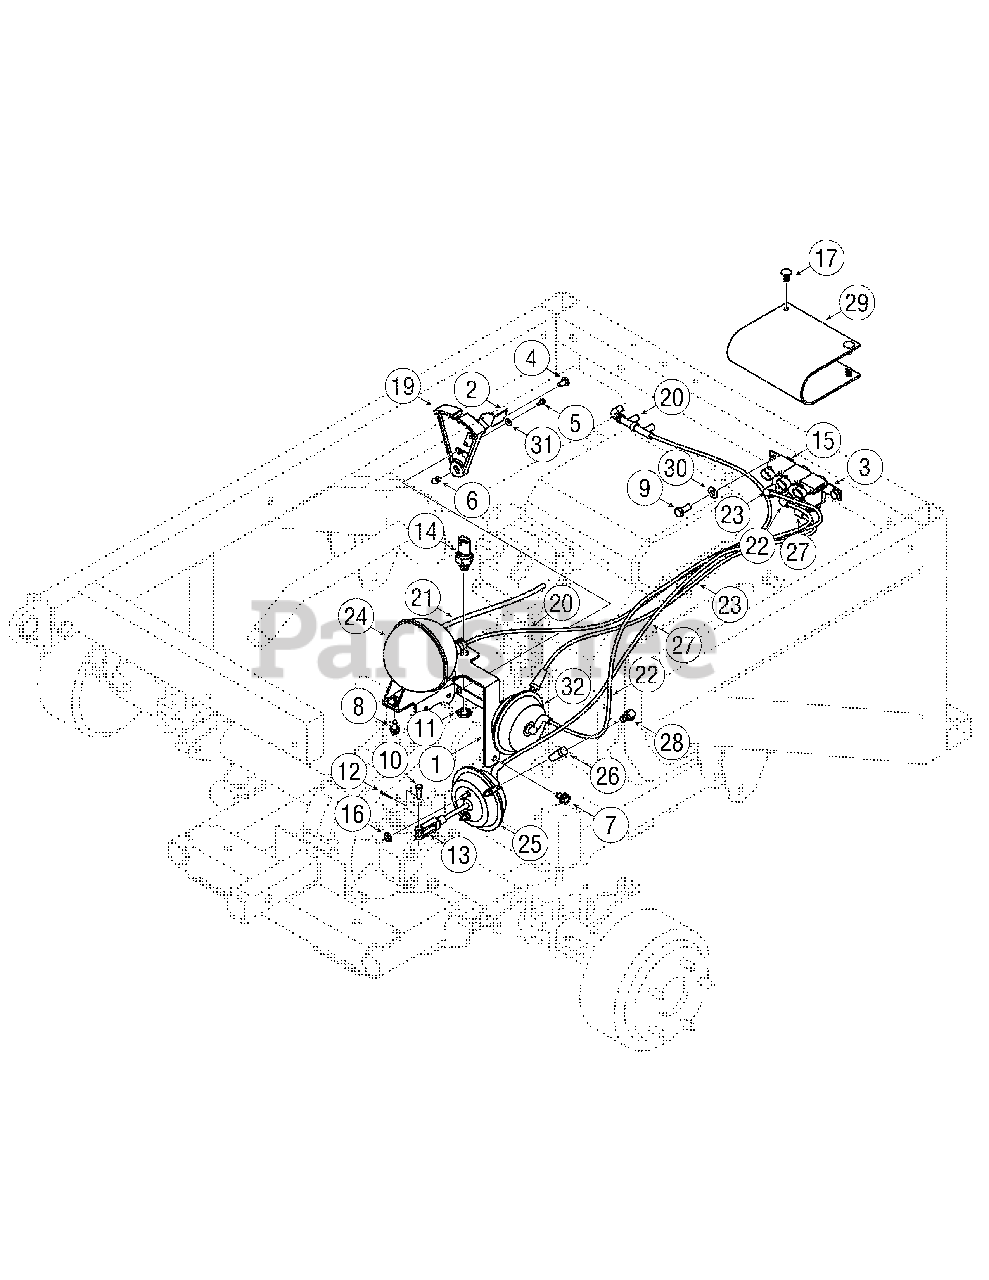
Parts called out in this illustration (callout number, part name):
1	Mounting Brkt., Vacuum Actuator
2	Bracket, Shift
3	Bracket, Vac Relay
4	Screw, 1/4-20 x.5
5	Screw, Hex. #8 - 18 .375
6	Screw, Set, 5/16-24 x .50 LG
7	Screw, 5/16-18
8	Screw, 1/4-14
9	Screw, 5/16-18 x .75 Hex
10	Pin, Yoke 1/4
11	Nut, Hex 9/16-18
12	Pin, Cotter 1/16x.750
13	Yoke, 1/4-28
14	Switch, Neutral
15	Solenoid, Kit Vacuum Actuator
16	Self Threading Nut
17	Clip, Panel Retainer
18	Cable Tie
19	Arm, Shift
20	Hose, Res
21	Hose, Manifold Vacuum
22	Hose, Actuator Vacuum
23	Hose, Actuator Vacuum
24	Reservoir, Air
25	Actuator, Vac Differential Lock
26	Ftg., Straight
27	Hose, Vac Differential Lock Supply
28	Vent, 3/8 Dia.
29	Cover, Solenoid
30	Flat Washer, .330 x .687 x .030
31	Flat, Washer, .188 x .437 x .042
32	Actuator, Vacuum Shift
